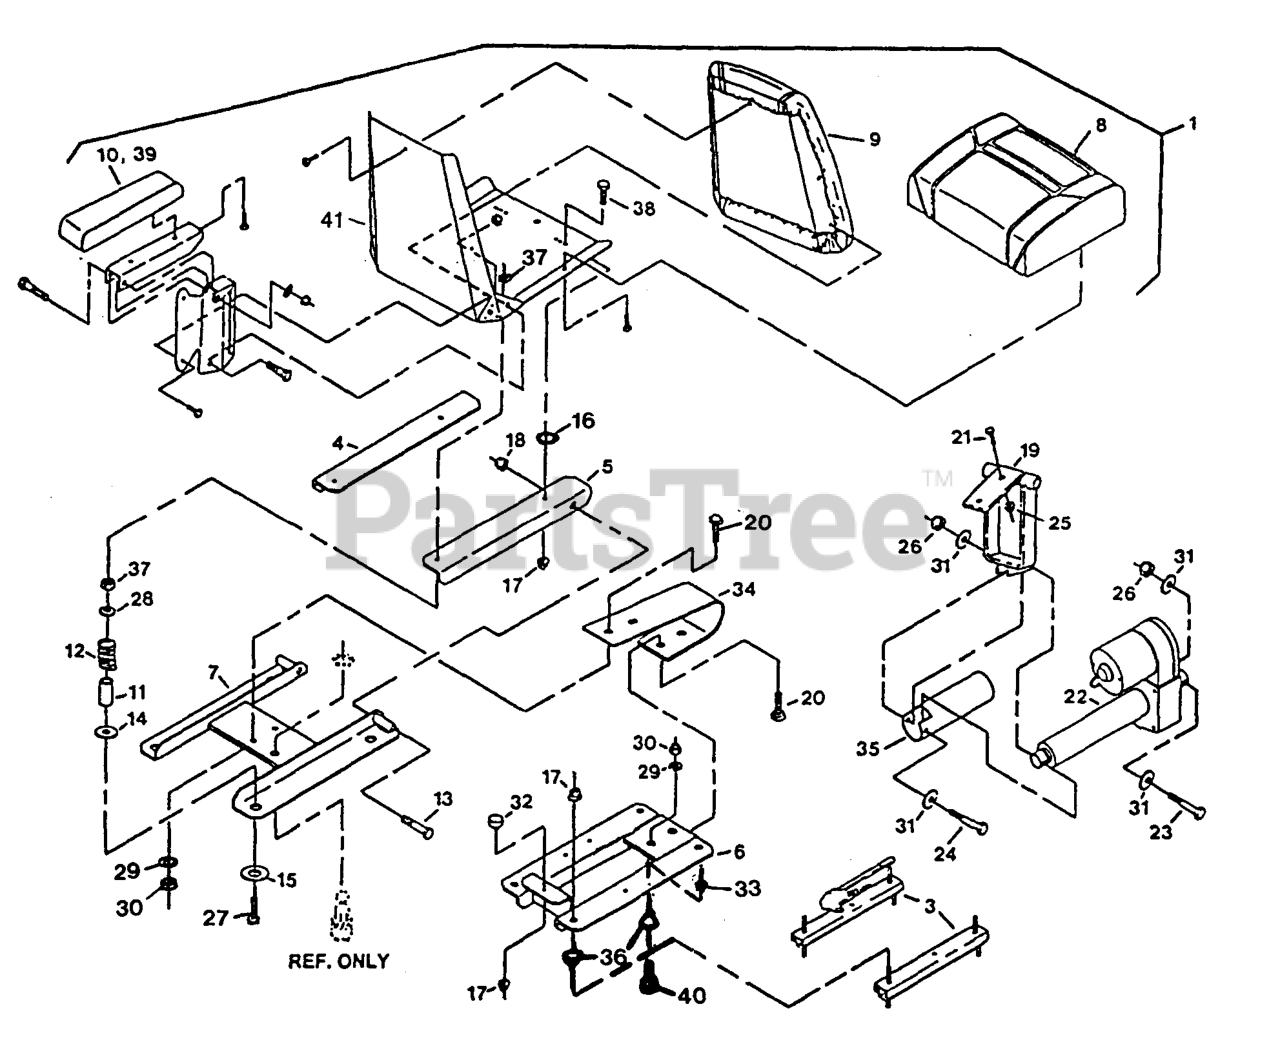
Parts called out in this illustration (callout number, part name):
4	RAIL,SEAT LH
5	RAIL,SEAT RH
6	WLD,RAIL BASE
11	BUSHING,SPRING GUIDE
12	SPRING-INDICATOR, REVERSE
27	BOLT,TAP HH
32	BUMPER-RUBBER
34	SPRING,RANGER SEAT
35	GUARD,ACTUATOR
36	SPACER-TRACK
41	FRAME-SEAT
